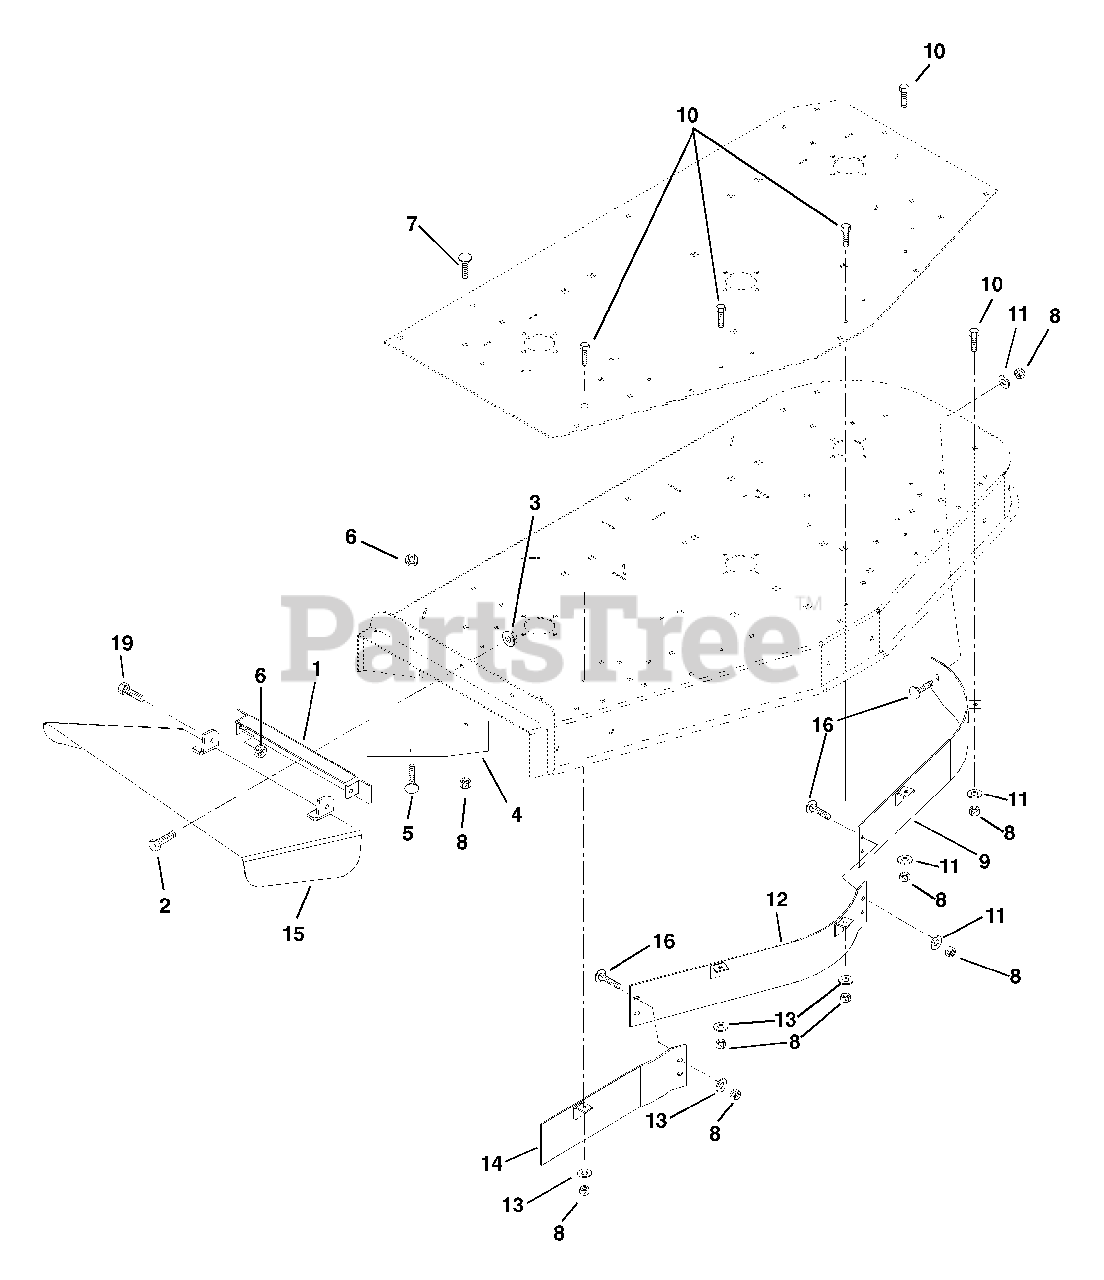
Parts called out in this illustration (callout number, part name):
1	Weldment, Discharge Chute Bracket
2	Bolt-Hex .38 - 16 x 1.00 Grade 5
3	Nut-Locking-Flange .38 - 16
4	Deflector, 60"
5	Bolt-Round Head Square Neck .38 - 16 x 1.00 Grade 2
6	Nut-Locking-Center .38 - 16
7	Bolt-Round Head Square Neck .31 - 18 x 1.00 Grade 5
8	Nut-Locking-Nylon .31 - 18
9	Weldment, 60" Left Hand Baffle-Upper
10	Bolt-Hex .31 - 18 x 1.00 Grade 5
11	Washer-Flat-Steel .312 x .734 x .065
12	Weldment, 60" Center Baffle-Up
13	Washer-Flat-Steel .312 x .734 x .065
14	Weldment, 60" Right Hand Baffle-Upper
15	Weldment, Discharge Chute 60"
16	Bolt-Round Head Square Neck .31 - 18 x .75 Grade 2
17	60" Mulching Kit
18	60" Discharge Cover
19	Bolt-Shoulder .38 - 16 x .38 Socket Head
